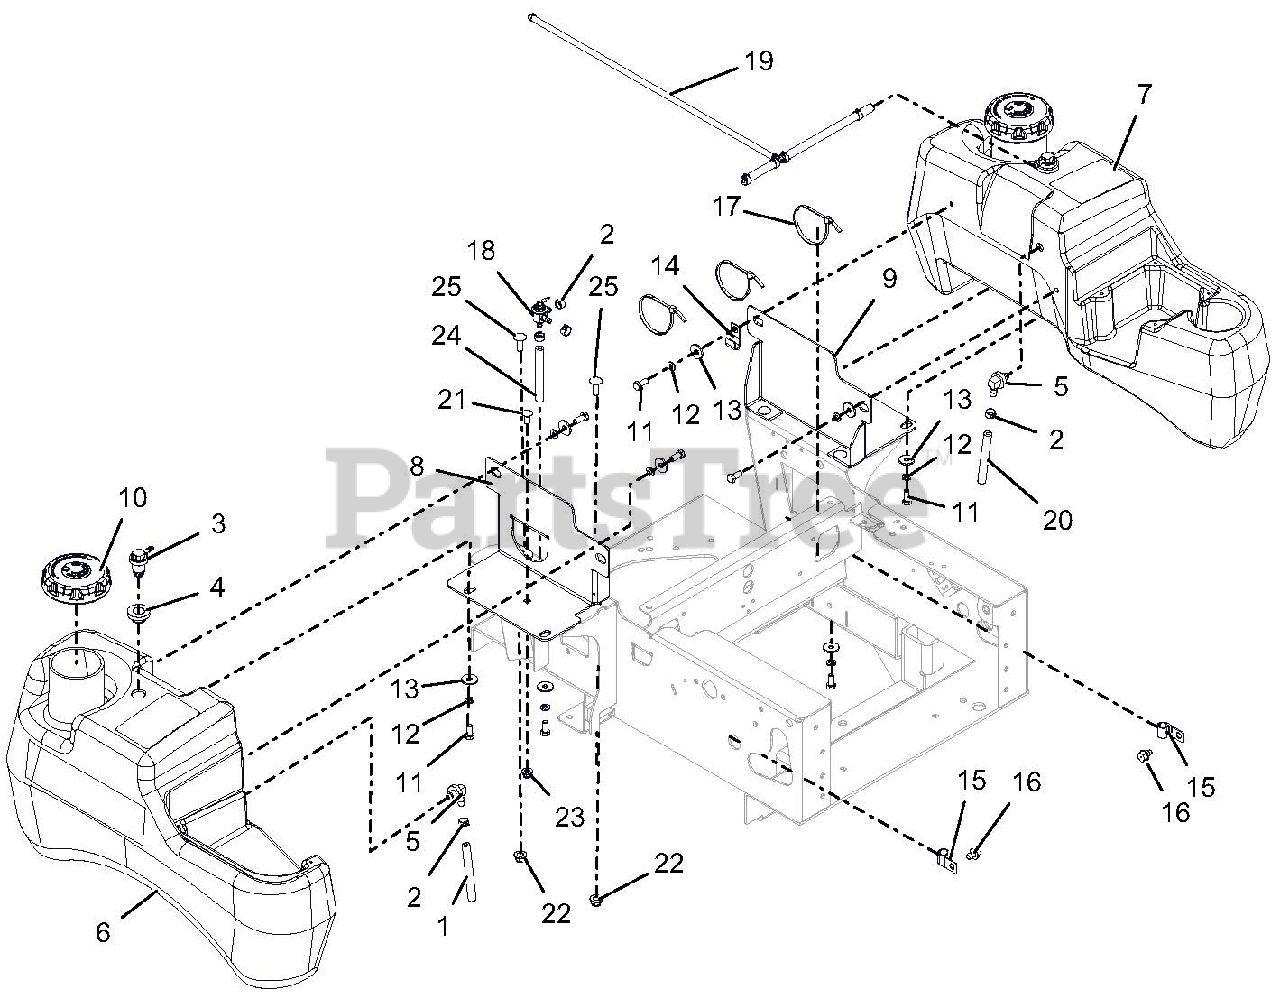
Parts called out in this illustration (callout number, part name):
1	.25 LOW-PERM GAS HOSE 18.50" LG - RH TANK TO VALVE
2	CLAMP, FUEL LINE
3	VALVE, 2-WAY
4	GROMMET, REMOTE VENT NITRILE
5	ASS’Y, SMALL/ MED TANK FUEL PICK-UP
6	TANK, GAS - RH MEDIUM GRAVELY
7	TANK, GAS - LH MEDIUM GRAVELY
8	BRKT, RH MEDIUM FUEL TANK MTG (RED)
9	BRKT, RH MEDIUM FUEL TANK MTG (RED)
10	CAP, FUEL VENT-IN AUTOLOCK
11	BLT-HEX .31-18X.75 GR5 YWZC
12	WSHR-LK .31X.078 REG YWZC
13	WSHR-FL-STL .328X1.00X.094 YWZC
14	CLAMP, J
16	SCR-TAP .38-16X.50 HWH TR YWZ
17	CABLE, TIE 5.50 LG
18	VALVE, FUEL
19	PT100, KAW FUEL LINE ASSEMBLY
20	.25 LOW-PERM GAS HOSE 40.00" LG - LH TANK TO VALVE
21	BLT-RDHDSQNK .31-18X.75 G5 YWZC
22	NUT-LK-NYL-FLG .38-16 YWZC
23	NUT-LK-NYL-FLG .31-18 YWZC
24	.25 LOW-PERM GAS HOSE 25.00" LG - VALVE TO ENGINE
25	BLT-RDHDSHSQNK.38-16X1.0 G5YZ
